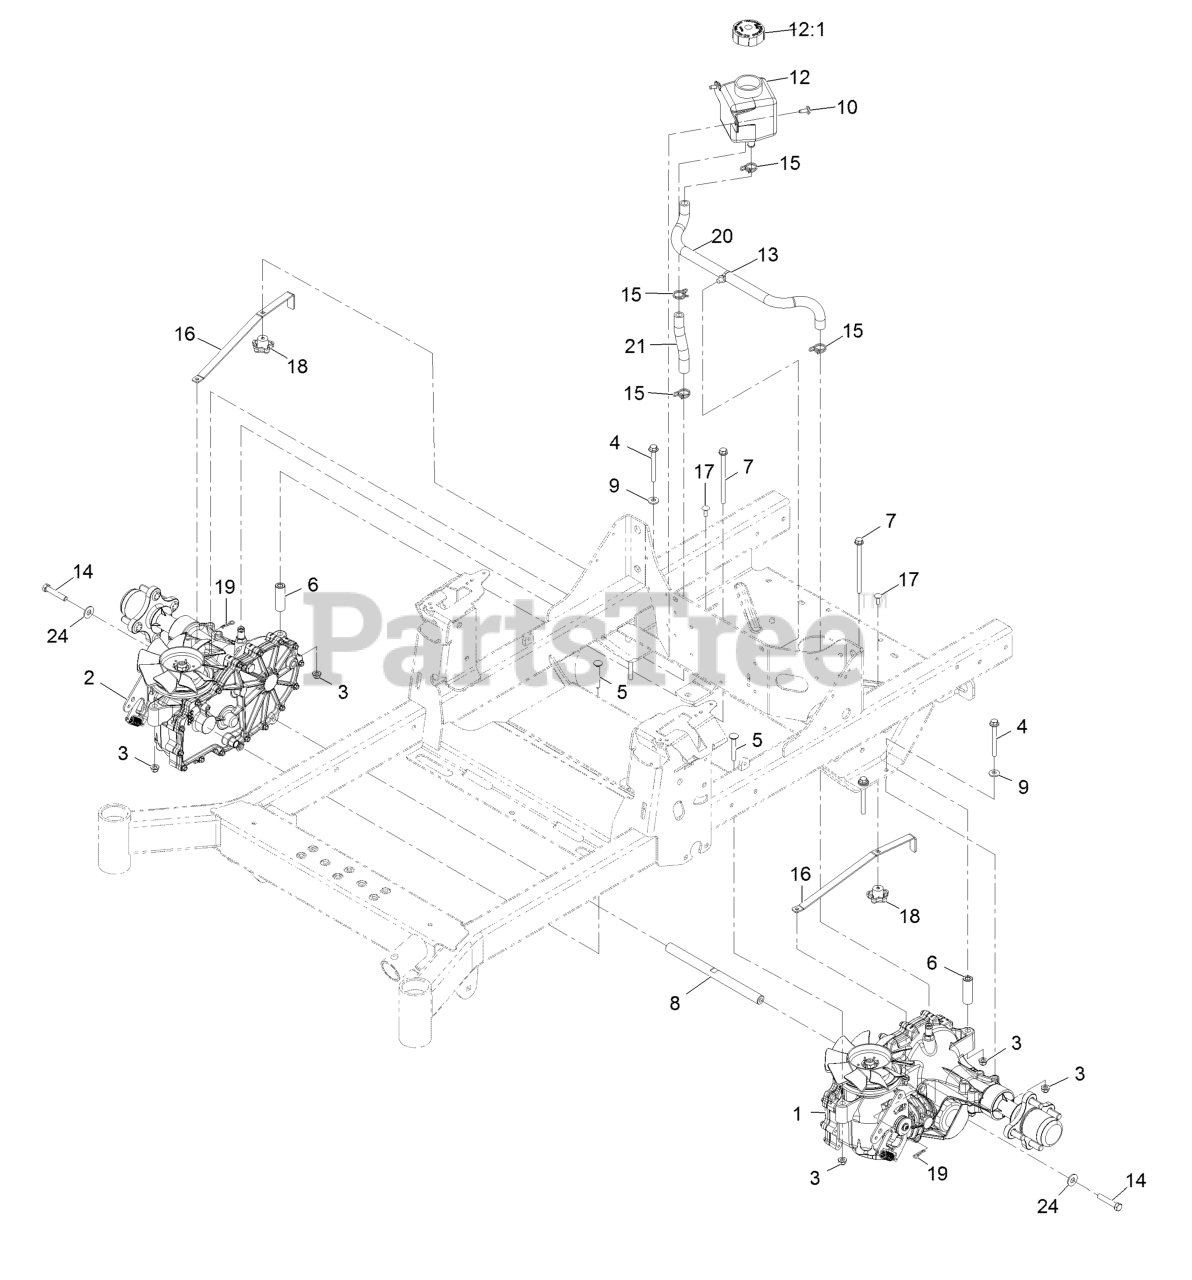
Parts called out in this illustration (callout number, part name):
1	Transaxle ASM LH
2	Transaxle ASM RH
3	Nut-Nyloc 5/16-18 Flg
4	Screw-HHF
5	Bolt-Carriage 5/16-18 X 2 1/4
6	Spacer-Hydro
7	Screw HHF
8	Shaft-Spacer
9	Washer-Spring Disc 5/16
10	Screw-1/4-20 X .65 Torx Plus
12	Tank-HYD
12:1	Cap-Reservoir, HYD
13	Clip-Tie
14	Screw-HH W/Loctite
15	Clamp-Hose
16	Arm-Bypass, Hydro
17	Bolt-Carriage 1/4-20 X 3/4
18	Knob-Handle
19	Hairpin-Cotter
20	Hose-Hydraulic
21	Hose-Hydraulic
24	Washer-3/8 Std
